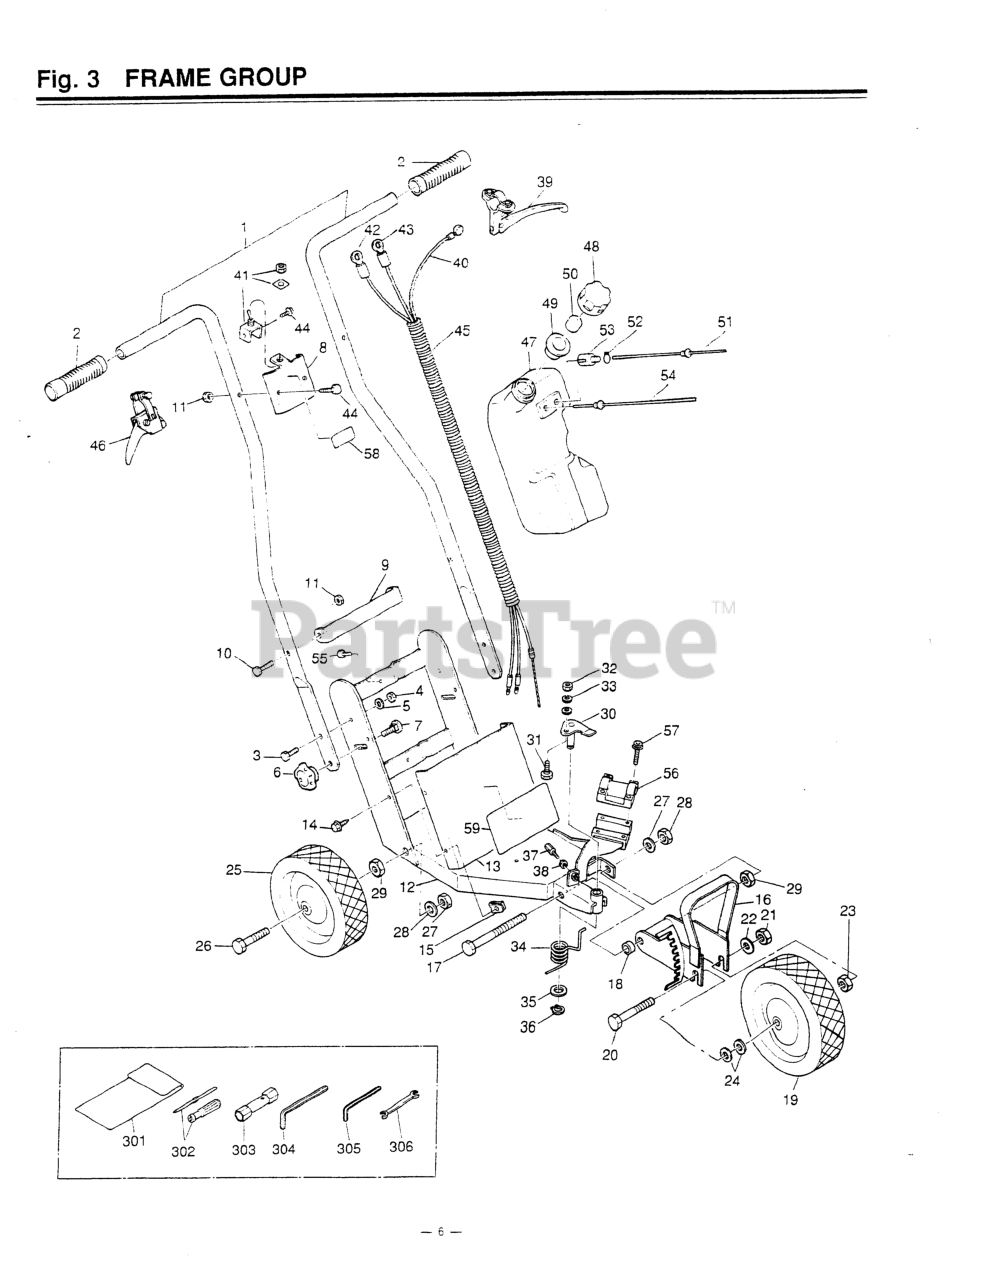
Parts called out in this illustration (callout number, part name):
7	BOLT, CARRIAGE
11	NUT, LOCK
23	NUT, JAM
29	NUT, JAM
30	HOOK (NLA)
32	NUT, M6 X 5
33	WASHER, M6 X 2.3
34	SPRING (NLA)
36	RING, SNAP (RPLS 3130-13270)
38	NUT, CABLE ADJUSTER
42	CORD (A)
43	CORD (B)
45	TUBE (NLA)
46	LEVER (NLA)
47	TANK ASSEMBLY
48	CAP ASSEMBLY (USE 3490-23203)
52	CLIP (REPLACES 2841-31280)
53	5500-85400 (RRLS. 1750-85300)
55	SCREW, M5 X 10
58	NAME PLATE
59	PLATE, WARNING
302	SCREWDRIVER
304	WRENCH (TOOL)
305	WRENCH (TOOL)
306	SPANNER, 8 X 10 (RPLS 2540- )
